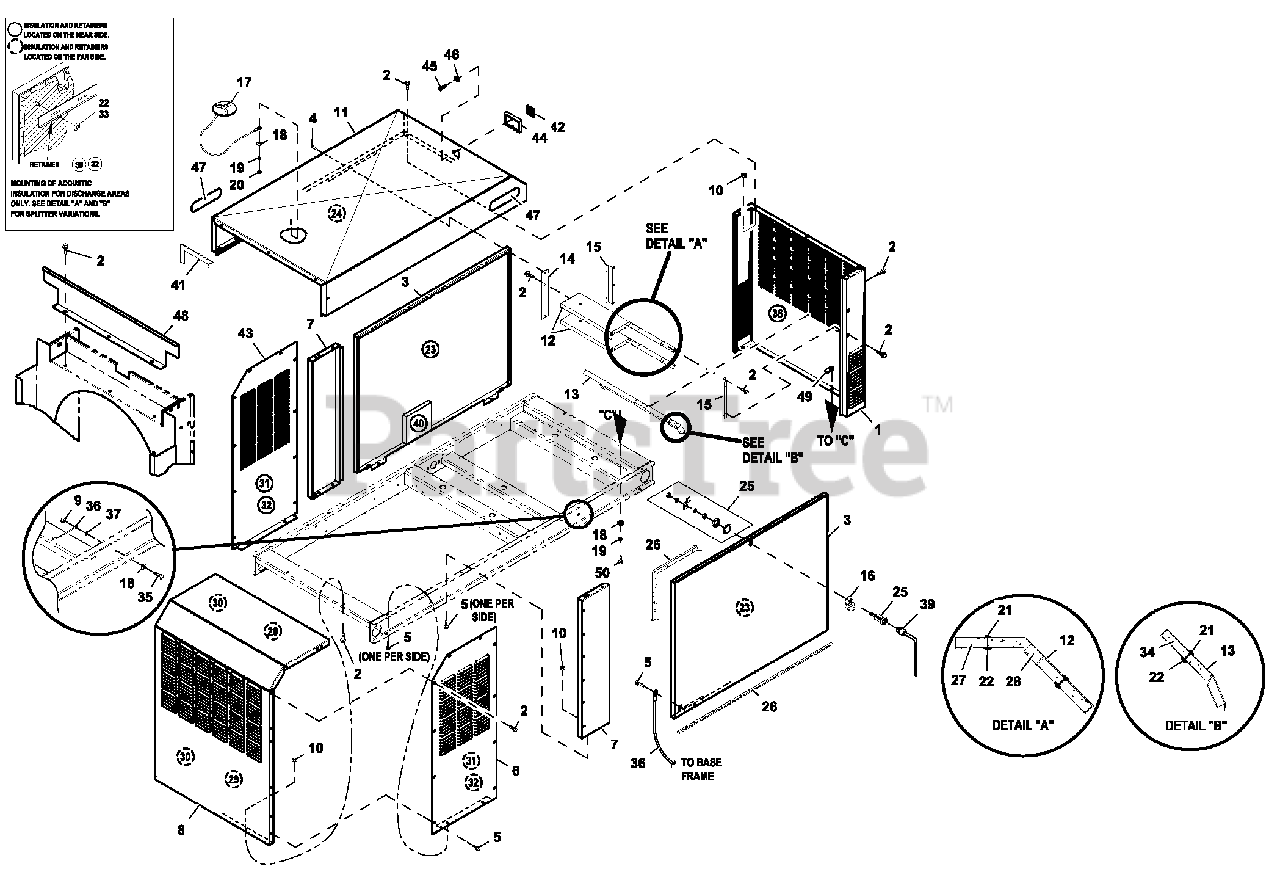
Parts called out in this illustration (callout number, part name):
1	REAR WRAP C2 CPL
2	SCREW THF M6-1 X 16 N WA Z/JS
3	D OOR C2
4	RIVET POP.1875 X .450 SS
5	SCREW TH-FRM M6 W/CAP SHKPRF W
6	D UCT DISCHARGE LH C2 AL
7	FRONT CORNERS C2
8	D UCT DISCHARGE MI D C2
9	NUT HEX M 6X1.0 G8 YELCHR
10	NUT HEX LOCK M6-1.0 SS NY INS
11	ROOF C2 CPL PVT LBL
12	SLITTER C4
13	SPLITTER LOWER C4
14	SPLITTER STRINGER C2
15	SUPPORT SPLITTER LHC2
16	TAB PULL
17	ASSEMBLY COVER ACCESS
18	WASHER FLAT 1/4-M6 ZINC
19	WASHER LOCK M6-1/4
20	NUT HEX 1/4-20 STEEL
21	INSULATION RETAINMENT HANGER
22	WASHER SELF LOCKING DOME #4-40
23	INSULATION D OOR C2
24	INSULATION ROOF TOP
25	VISE-ACTION LATCH SLOTTE D CIR
26	GASKET EXTRUDED TRIM (328" LG)
27	INSULATION SPLITTER
28	INSULATION SPLITTER
29	INSULATION D UCT
30	RETAINER INSULATION (820)
31	INSULATION D UCT SI D ES
32	RETAINER INSULATION (450)
33	WASHER SELF LOCKING DOME #8-32
34	INSULATION LOWER SPLITTER
35	SCREW HHC M6-1.0X20 G8.8
36	ASSY WIRE 14 AWG 34.8" GRN/YEL
37	WASHER SHAKEPROOF INT 1/4
38	INSULATION REAR WRAP
39	KEY VISE-ACTION LATCH SLOT CIR
40	FOAM 300 X 300 THERMAL ACO (APPLIES TO 4.2L UNITS ONLY)
41	STRIP SEALANT 1/8X 1 (44.52+LG)
42	RF COVER PLATE-PLASTIC- D RK GRY (OPTIONAL)
43	D UCT DISCHARGE RH C2 AL
44	ASSY ENCLOSURE GEN SI D E RF
45	SCREW PPPH M3X12
46	WASHER FLAT M3
47	BA DGE, HONEYWELL
48	BAFFLE TOP EXHAUST C2 HW
49	NUT UM6-1.0 GEOMET
50	SCREW HHFC M6-1.0X 2 0 G8.8
